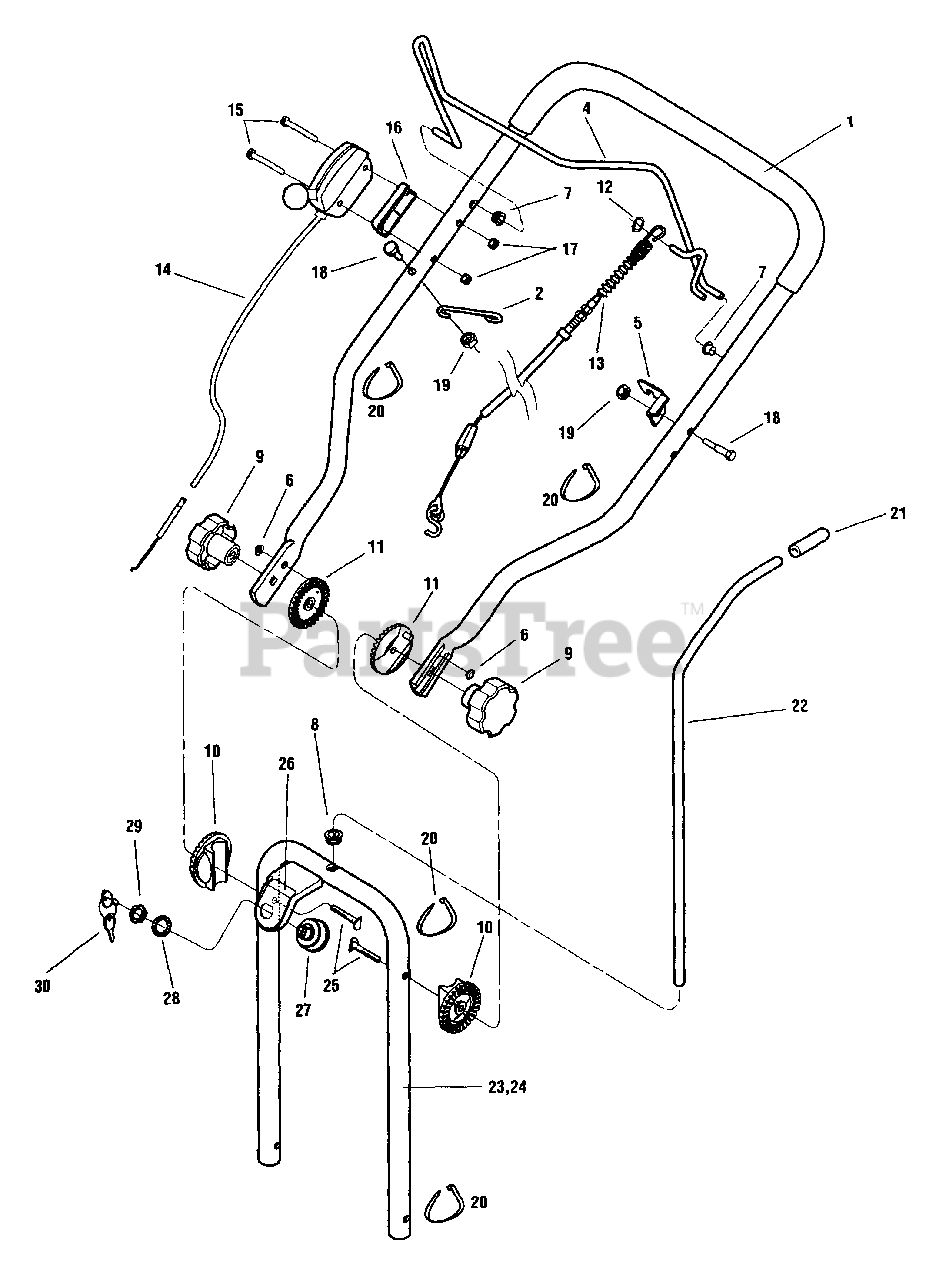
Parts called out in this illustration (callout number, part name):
1	Upper Handlebar w/sleeve
2	Rope Guide
5	Cable Bracket
6	Push-on Retainer
7	Nyliner Bushing
8	Nyliner Bushing
9	Adjusting Knob
10	Inside Hndlbr. Adj. Quadrant
11	Outside Hndlbr Adj. Quadrant
12	Retaining Ring, external .312" I.D.
13	Control Cable
14	Throttle Cable
15	Screw, 10-24 x 2
16	Spacer
17	Lock Nut, 10-24
18	Hex Hd Screw, 1/4-20 x 1-1/8
19	Top Lock Nut, 1/4-20
20	Cable Tie
21	Steering Rod Grip
22	Upper Steering Rod
23	Lower Handlebar
24	Lower Handlebar
25	Curved Hd Bolt, 5/16-18 x 2
26	Decal-Keyswitch
27	Ignition Switch
28	Lockwasher, 5/8
29	Hex Nut, 5/8-32
30	Ignition Key
